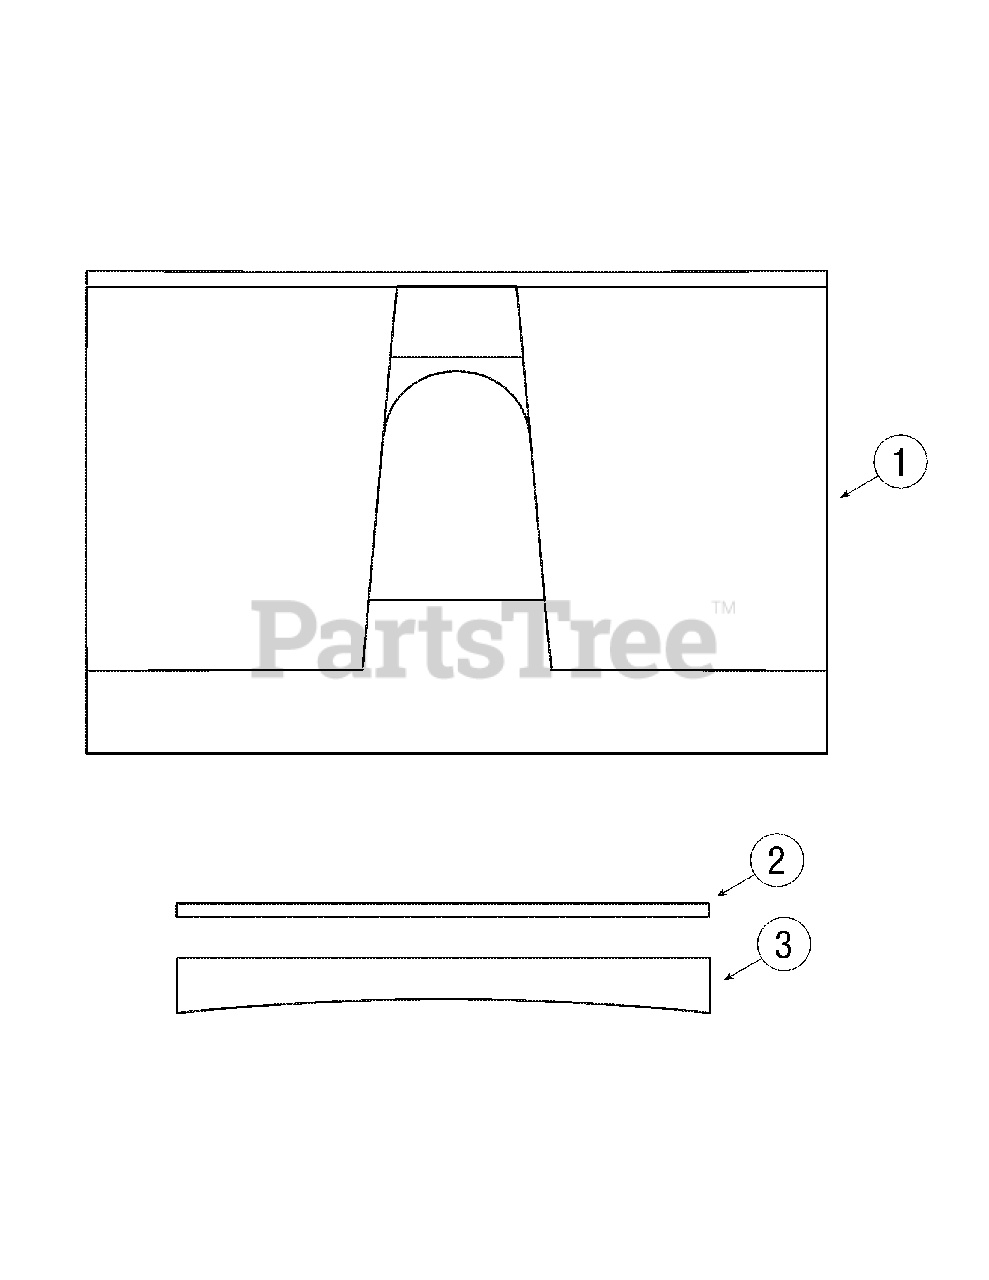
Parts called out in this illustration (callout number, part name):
1	Soft Roof
2	Windshield Velcro
3	Lower OPS Skirt
